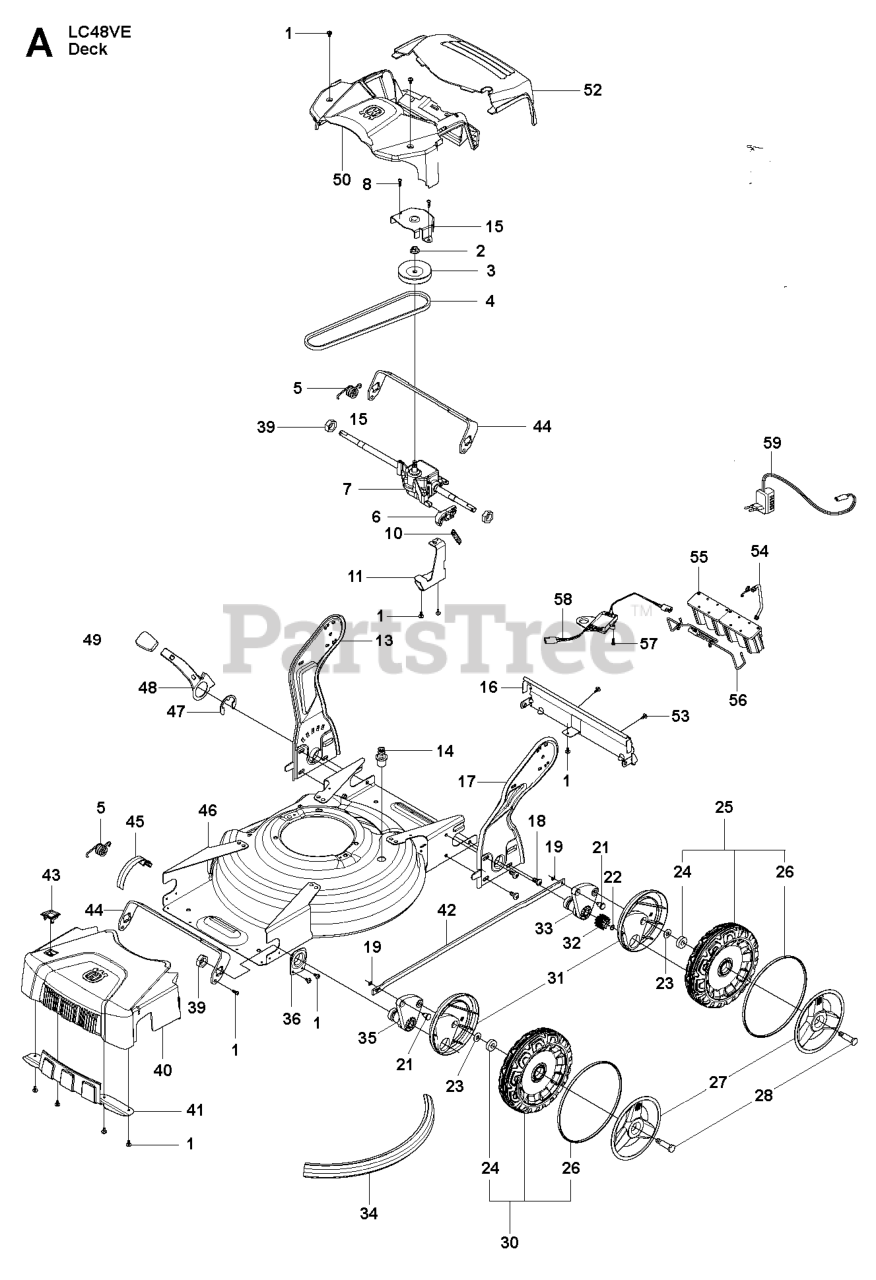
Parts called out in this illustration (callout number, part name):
1	SCREW ITXPANTT M5X10 ZPB (A00
4	BELT WRAPPED V-BELT Z 29.5
8	SCREW ITXPANT T50X16 ZN/FE (A
19	FASTENER
24	BALL BEARING
46	CHASSIS 48S A009 PAINTED
53	SCREW ITXPANTT M5X10 ZPB (A00
